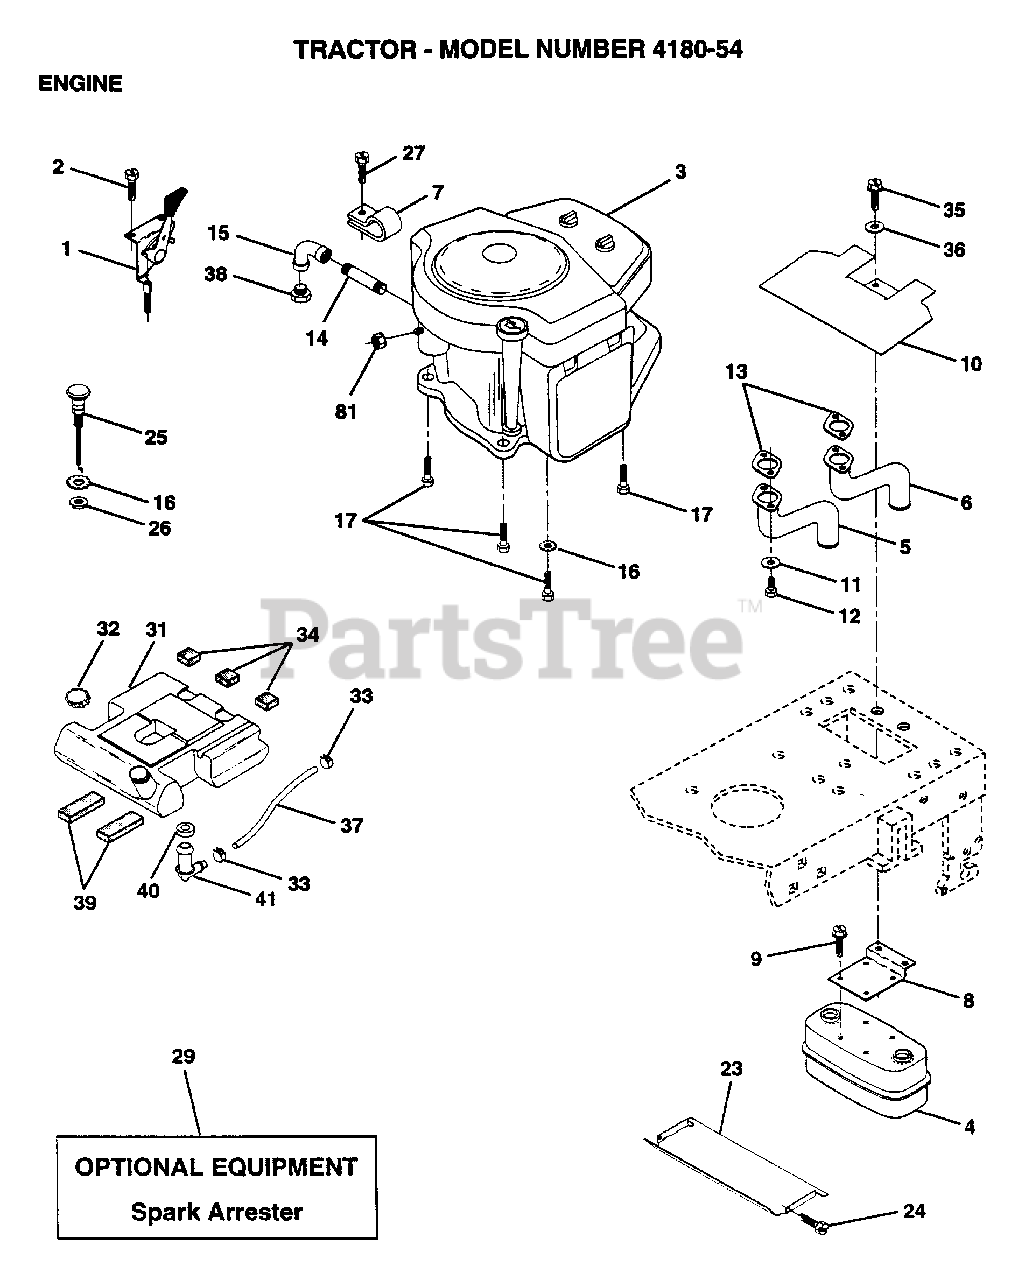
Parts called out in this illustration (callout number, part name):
2	SCREW LT
3	ENGINE, B&S
5	EXHAUST.B&S.18.LH
6	EXHAUST.B&S.18.RH
7	CLAMP.TUBE.DBL.EN
8	BRACKET MUFFLER
9	SCREW ST
10	SHIELD.HEAT.
11	LOCKWASHER
14	PIPE NIPPLE LT
15	ELBOW
16	LOCKWASHER
17	SCREW LT
18	HEAT SHIELD
19	RECEPTACLE LT
20	RETAINER LT
22	STUD.1/4.TURN
23	HEAT SHIELD
24	SCREW
25	"CONTROL.CHOKE.51"""
27	SCREW.10-24X1/2
32	CAP ASM FUEL
33	HOSE CLAMP
34	PAD-SPACER LT
35	SCREW
36	WASHER
37	FUEL LINE T
39	PAD IDLER TI
40	BUSHING OUTLET T
41	STEM.TANK.FUEL
81	NUT
